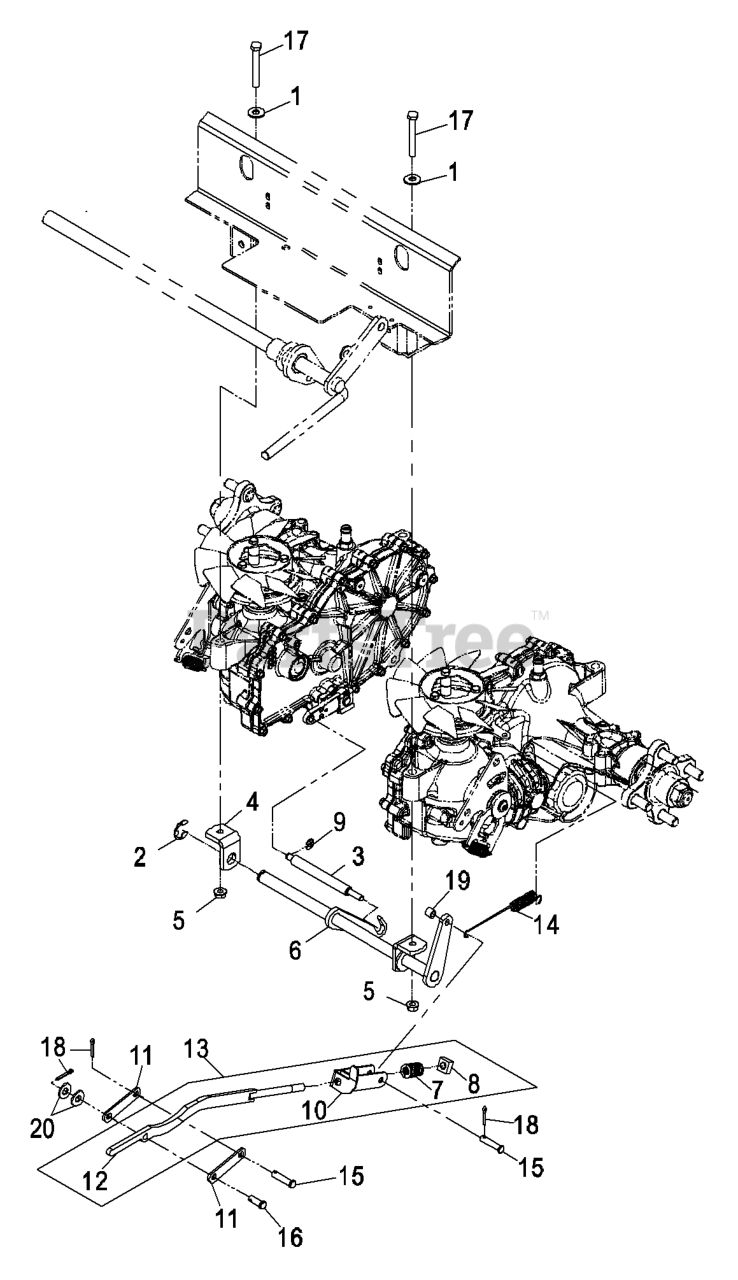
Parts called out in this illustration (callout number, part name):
1	WASHER-FLAT
2	E-RING
3	BAR-EQUALIZER
4	BRACKET-PIVOT, BRAKE
5	NUT-HF, NI
6	Wld, Brake Bellcrank
7	SPRING-BRAKE
8	NUT-SQUARE
9	RING-RETAINING, EXT
10	CLEVIS-BRAKE
11	LINK-CENTER, OVER
12	LINK-BRAKE
14	SPRING-RETURN, BRAKE
15	PIN-CLEVIS
16	PIN-CLEVIS
17	SCREW-HH
18	PIN-COTTER
20	WASHER-PLAIN
